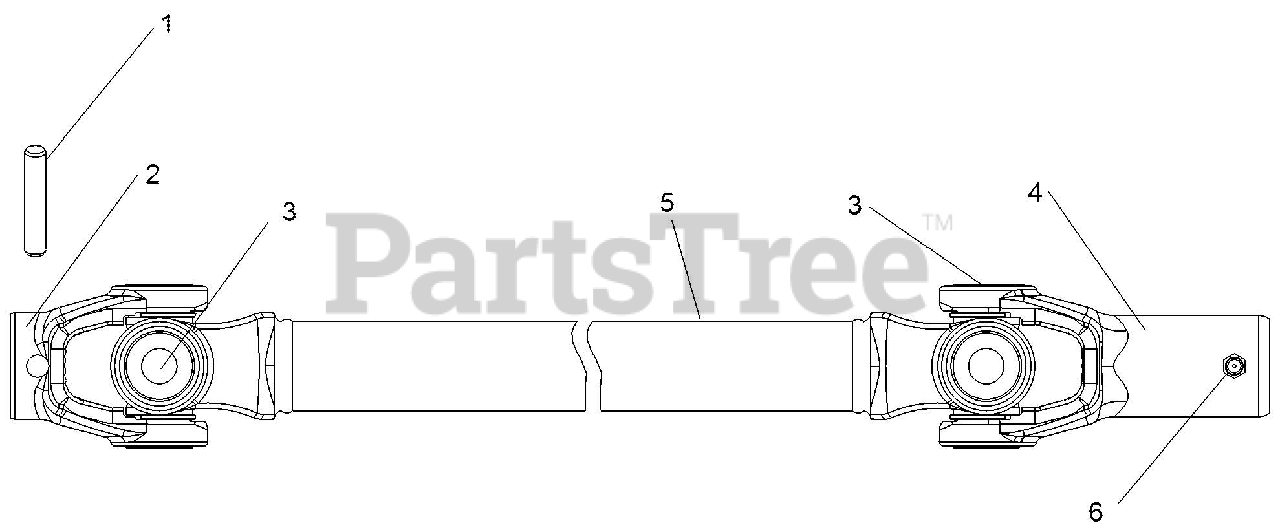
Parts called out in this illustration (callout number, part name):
1	PIN,SPRING(10)
3	KIT,CROSS & BEARING,NONGREASE
4	YOKE-SLIP (6272008)
5	SHAFT, PROP
5	ASM-PROPSHAFT,FRONT
6	FITTING, LUBRICATION
